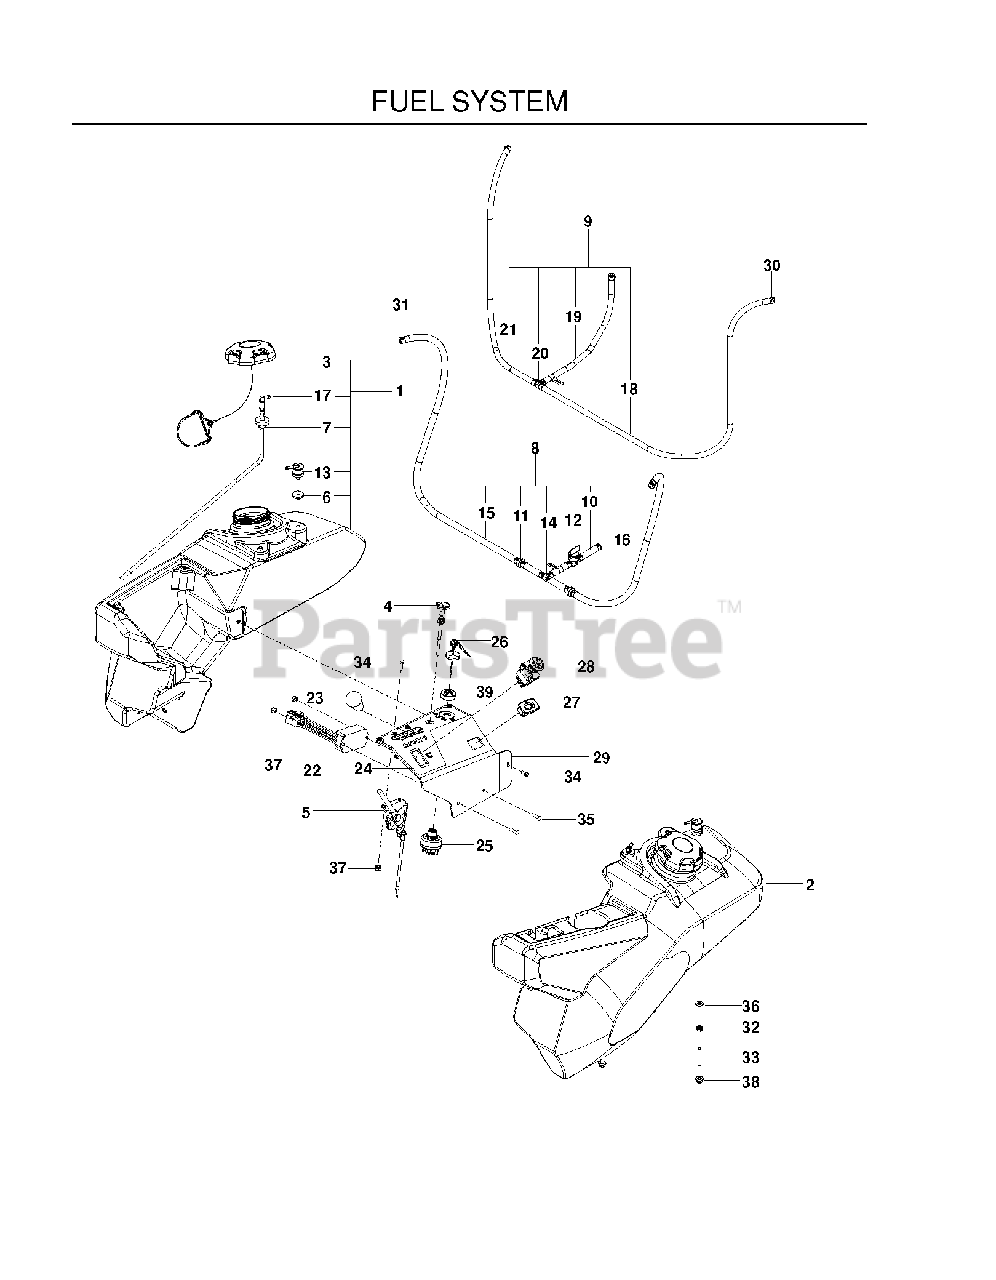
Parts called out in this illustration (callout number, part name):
3	CAP, FUEL
6	RUBBER GROMMET
7	GROMMET, CHECK VALVE
10	FUEL LINE - 2.5"
11	VALVE, CHECK, .25
12	FUEL VALVE
13	VALVE, FUEL CHECK
14	TEE, FUEL LINE, .25
15	FUEL LINE 29.5"
16	FUEL LINE
21	FUEL LINE 33"
22	TIMER, SEAT
23	KNOB - SHIFT
25	SWITCH, IGNITION, INDAK
26	KEY, IGNITION
27	HOUR METER
28	SWITCH, PTO 10 AMP
30	CLAMP, HOSE
31	HOSE CLAMP
33	STUD, 5/16C
34	SCR #10-24 X 3/8 SKT HD BLK OX
35	SCR #10-24 X .75 SKT HD BLK
36	FLAT WASHER 5/16 SAE
37	NUT 10-24 NYLOC
38	5/16-18 NYLOC FLANGE NUT
